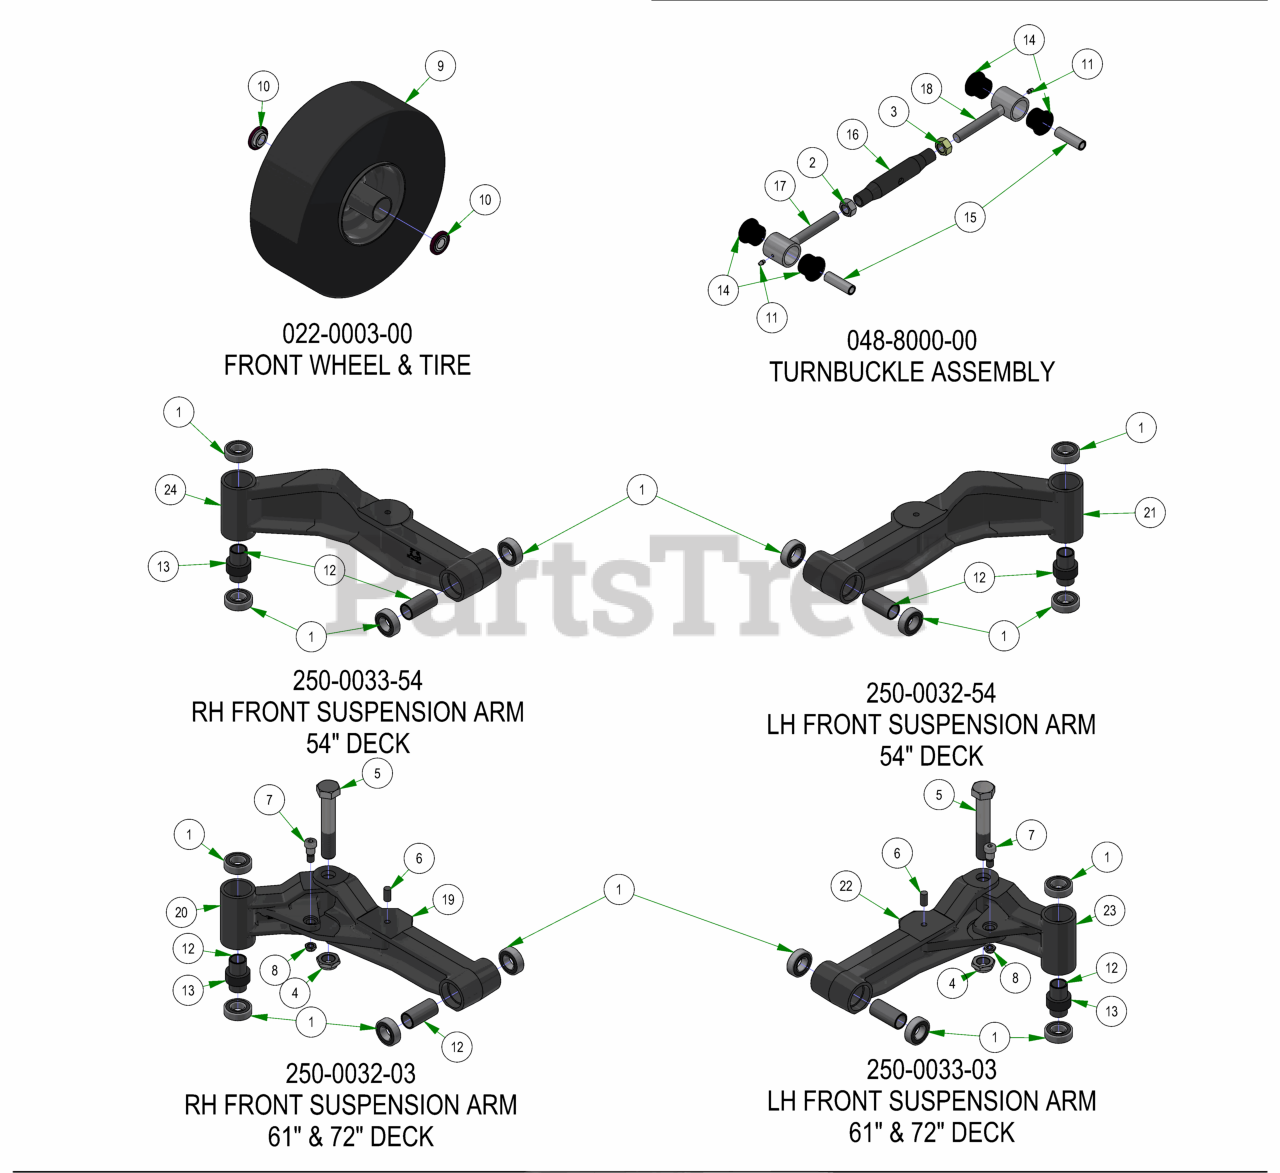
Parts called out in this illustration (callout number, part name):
1	1641 BEARING W/2 CONTACT RUBBER SEALS
2	Hex Nut M20-2.5
3	Hex Nut M20-2.5 Left Hand Threads Gold Plated
4	1"-14 NYLON INSERT JAM LOCKNUT ZINC
5	1"-14 X 5-1/2 HEX CAP SCREW (GR.8) ZINC YELLOW
6	1/2-13 x 1" Stud
7	5/8 X 5/8 SOCKET SHOULDER BOLT ZINC YELLOW
8	1/2-13 NYLON INSERT JAM LOCKNUT ZINC
9	15x6-6 Tire Only
10	1-3/4" Bearing-Large Bore Front Rim
11	1/4-28 Grease Fitting
12	2016 Front Bearing Spacer
13	Rubber Stabilizer (Front Forks) [R series]
14	Polyeurethane Bushing
16	2024 Turnbuckle Body
17	Turnbuckle End Right-Handed Thread
18	Turnbuckle End Left-Handed Thread
19	INNER RH FRONT AXLE
20	OUTER FRONT ARM RH
21	2019 Front I-Beam Left - Black
22	INNER FRONT ARM LH
23	CAST OUTER ARM LH
24	R.H. I-BEAM ARM - Black
